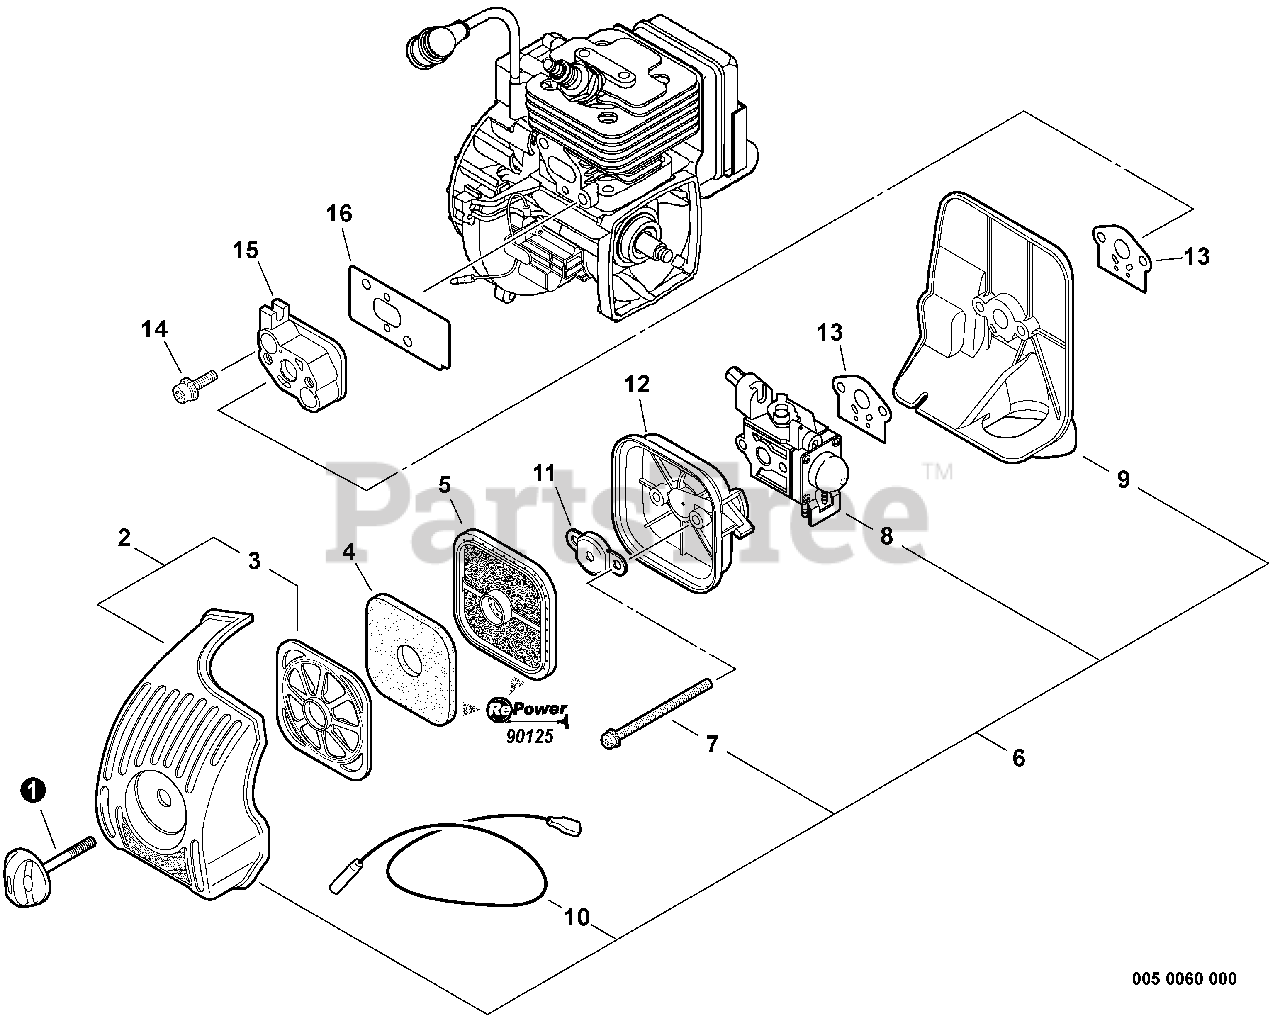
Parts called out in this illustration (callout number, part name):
1	GASKET KIT
2	GASKET, CRANKCASE
3	GASKET, CYLINDER
4	HEAT SHIELD, INTAKE
5	GASKET, INTAKE
6	HEAT SHIELD, EXHAUST
7	GASKET, EXHAUST
8	TUNE-UP KIT - REPOWER
9	PRE-FILTER, FOAM
10	FILTER, AIR - DOUBLE LAYER
11	FILTER, FUEL
12	SPARK PLUG - BPMR-8Y
13	FUEL SYSTEM KIT - REPOWER
14	VENT ASSY
15	CLIP 6.5MM
16	PIPE, VENT 3×6×35 BLACK
17	PIPE, FUEL 3×5×195 BLACK
18	PIPE, FUEL 3×6×75 CLEAR
19	GROMMET, FUEL
21	FILTER, FUEL 125-528
22	FUEL SYSTEM KIT - REPOWER
23	VENT ASSY
24	CLIP 6.5MM
25	PIPE, VENT 3×6×35 BLACK
26	PIPE, FUEL - 3×5×67 - BLACK
27	PIPE, FUEL 3×6×75 CLEAR
28	GROMMET, FUEL
29	CONNECTOR, PIPE 5×3.5
31	PIPE, FUEL - 3×5×125 - BLACK
32	FILTER, FUEL 125-528
33	GASKET, FUEL CAP
34	CAP/VENT KIT - REPOWER
35	CAP, FUEL
36	VENT ASSY
37	GASKET, FUEL CAP
38	PIPE, BULK - REPOWER 3×5mm BLACK
39	PIPE, BULK - REPOWER 3×6mm CLEAR
40	PIPE, BULK - REPOWER 3×6mm BLACK
41	ROPE, STARTER - REPOWER BULK 3
